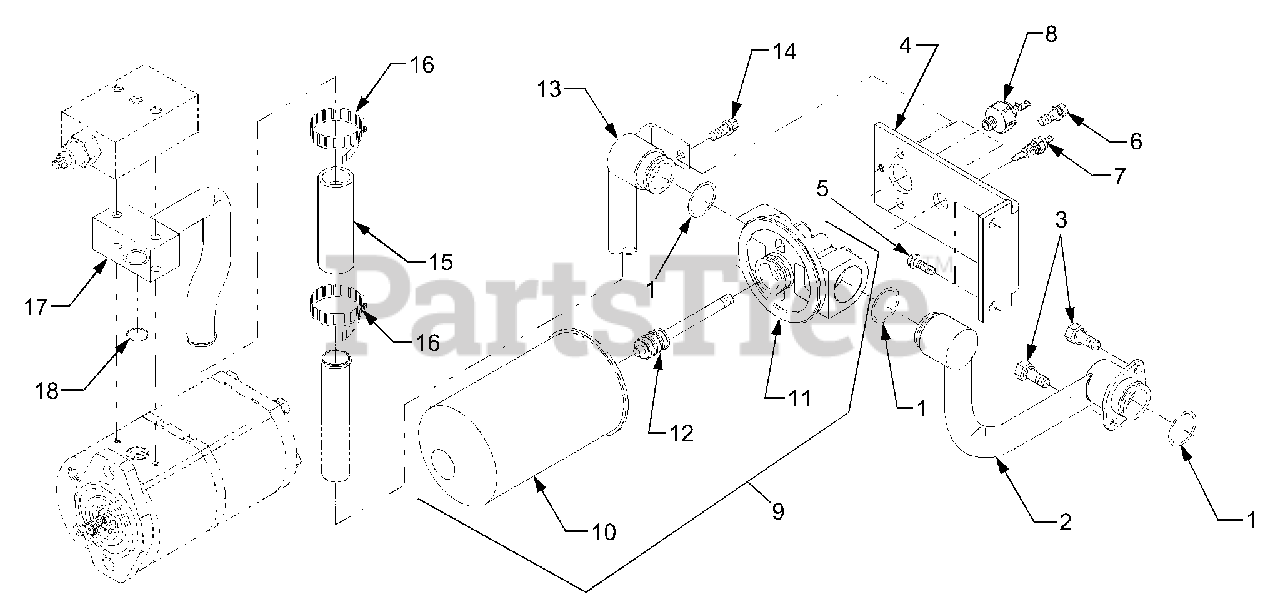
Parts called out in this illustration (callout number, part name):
2	Pipe 1, Suction
4	Supprot, Filter
7	Sensor, Thermostat
8	Sensor, Vacuum
9	Hydraulic Filter Ass'y
10	Filter, Hydraulic
11	Bracket, Filter
13	Pipe 2, Suction
17	Pipe 3, Suction
